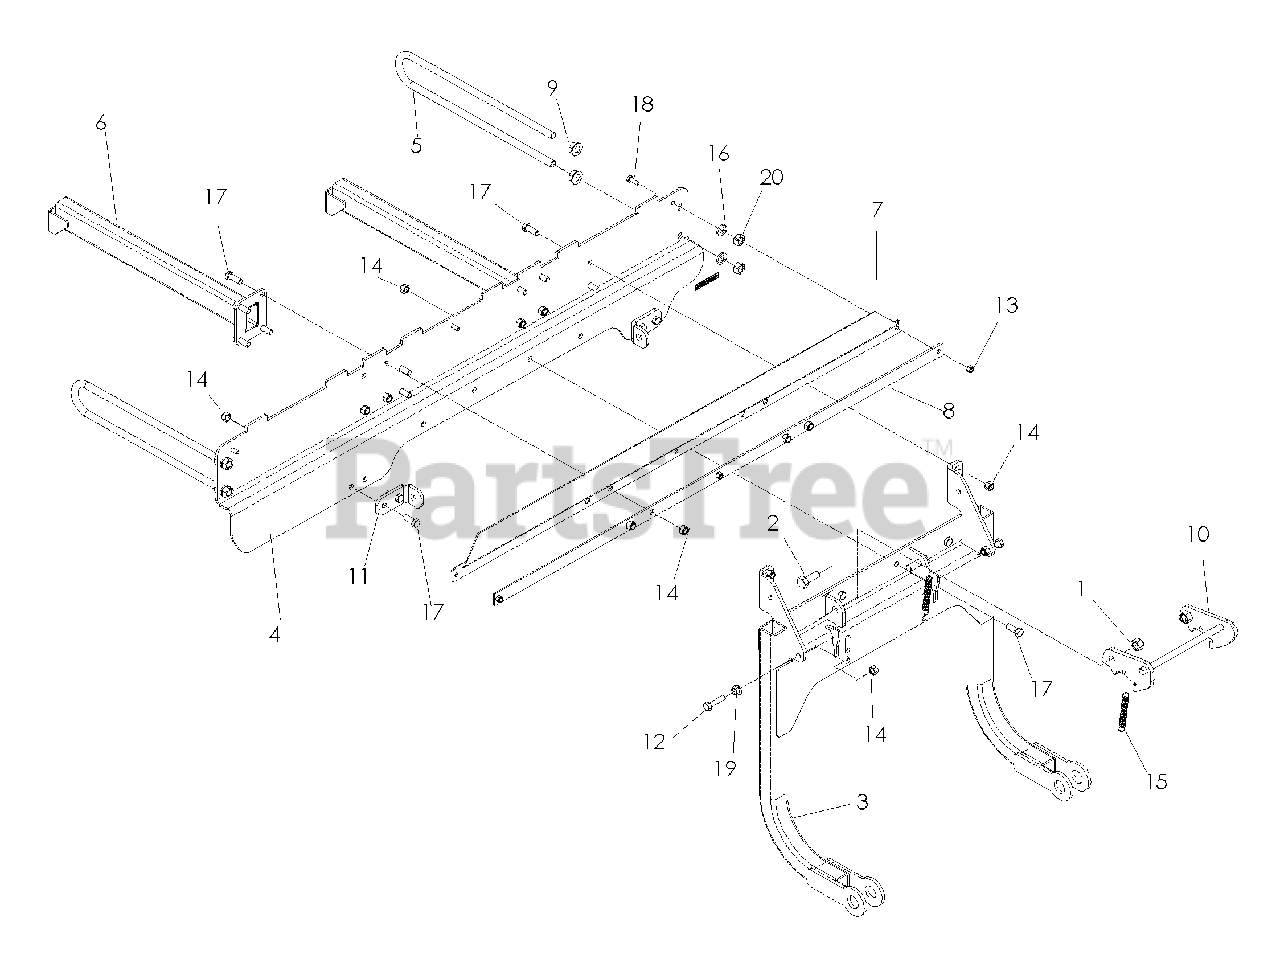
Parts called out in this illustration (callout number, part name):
1	NUT 1/2-13 HEX NYLOC
2	HCS 1/2-13 x 1 1/4
4	MOUNT Z BRACE
5	SUPPORT, OUTER
6	SUPPORT ARM
7	SEAL, RUBBER
8	SEAL STRAP
9	NUT 1/2-13, WHIZLK
11	BRACKET, SUPPORT
12	HCS 3/8-16 x 1/4
13	NUT 1/4-20 HEX NYLOC
14	NUT 3/8-16 HEX NYLOC
16	LOCKWASHER 1/2
17	HCS 3/8-16 x 1
18	HCS 1/4-20 x 3/4
19	NUT 3/8-16 HEX WHIZLK
20	NUT 1/2-13 JAM
